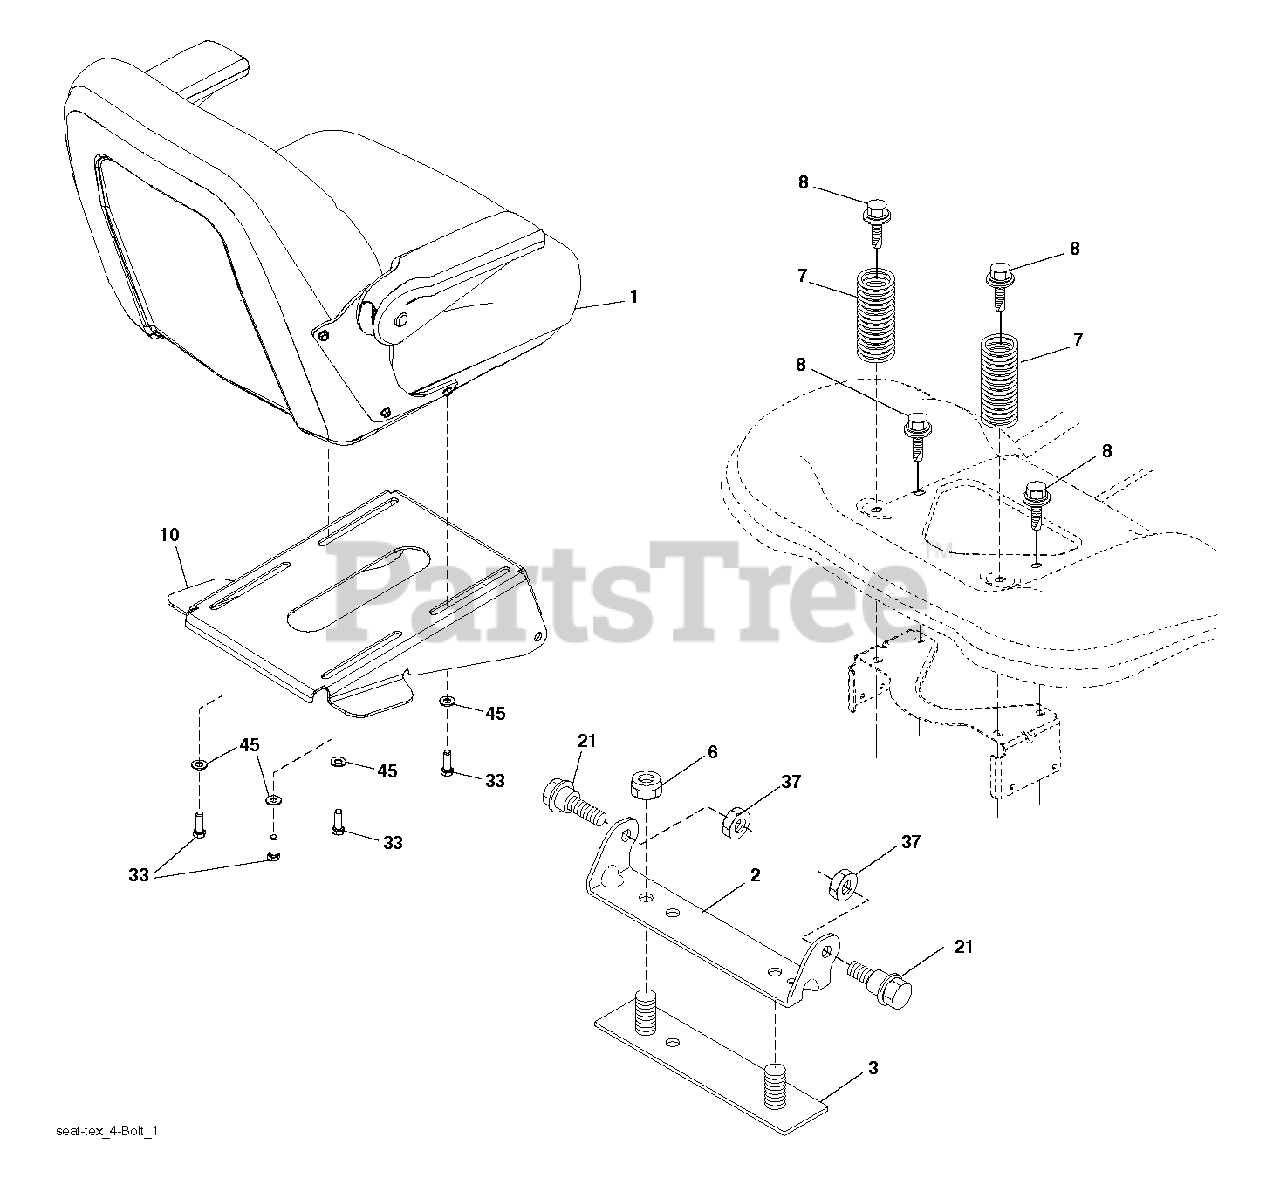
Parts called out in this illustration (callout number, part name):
1	SEAT.MILSCO.18".WITH.ARMREST
2	BRKT.PIVOT.FENDER
6	NUT
7	SPRING COMPRESSION
8	BOLT, 5/16-18 X 1 3/4
10	PAN.SEAT.4-BOLT.7.5X7.431
21	BOLT.SHOULDER.5/16-18
33	BOLT.FIN.HEX.5/16-18UNC X 1.00
37	NUT.71038.31-18.HEX.NYLOCK
45	WASHER
